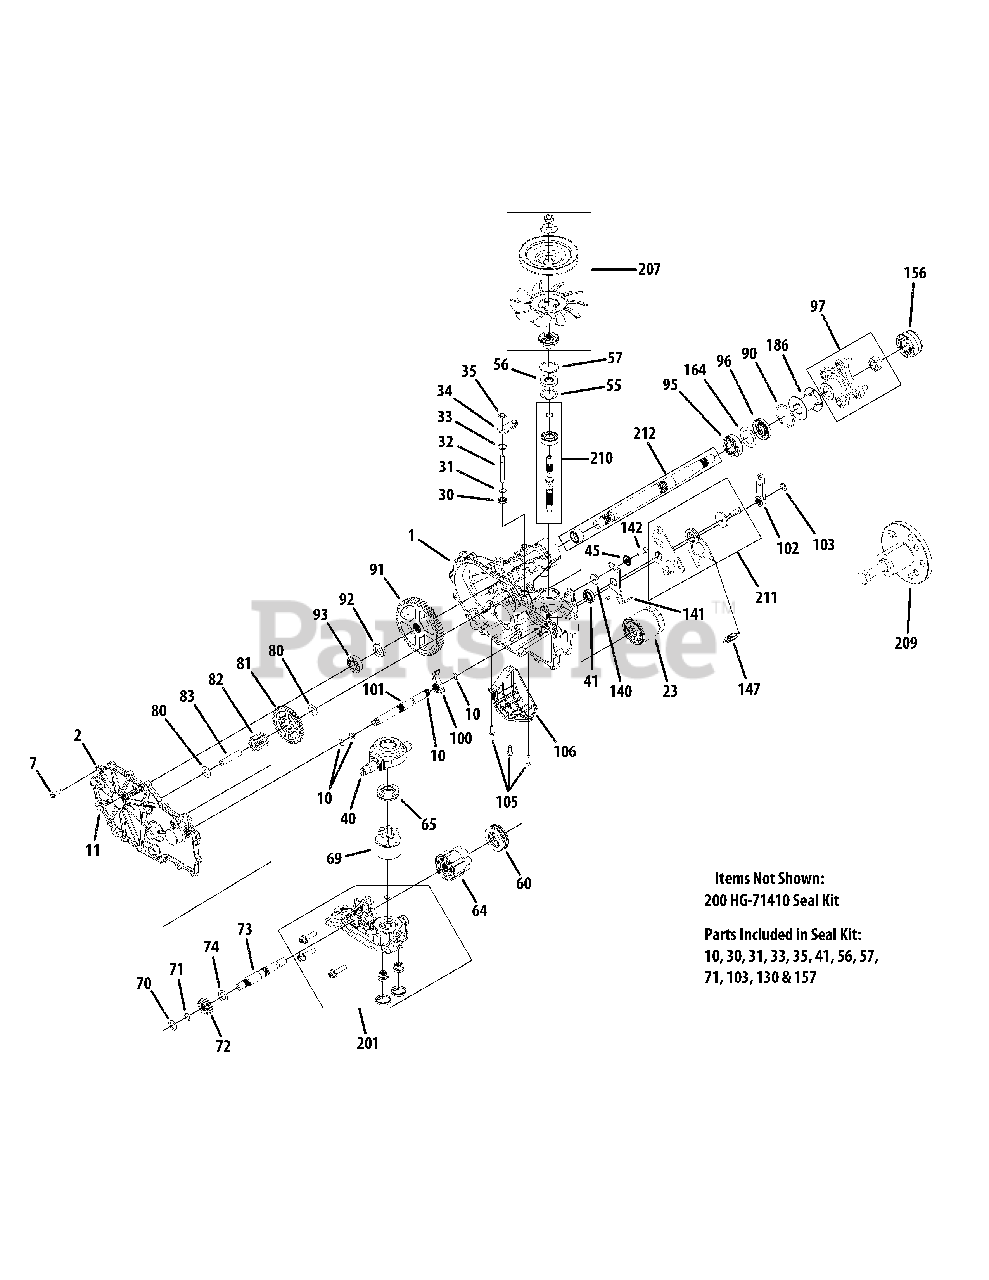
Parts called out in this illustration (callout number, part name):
1	Kit, Main Housing, LH Control
2	Kit, Side Cover, LH
7	Screw, Hex Washer
23	Filter, Spin-On 2.6 x 3.0
30	Seal, Lip, .375 x .75 x .25
31	Ring, Retaining .375 External
32	Rod, Bypass
33	Ring Retaining .750 Internal
34	Arm, Bypass
35	Ring, Ret .375 External
40	Trunnion, Swashplate
41	Seal, Lip 18 x 32 x 7
45	Washer, .34 x .88 x .06
55	Washer, 1.23 x 1.57 x .04
56	Seal, Lip 17 x 40 x 7
57	Ring Retaining Internal
60	Bearing, Thrust 35 x 62 x 18
64	Kit, 16cc Cylinder Block Assembly
65	Thrust Bearing, 30 x 52 x 13
69	Kit, Block, 7 Piston
70	Washer, .63 x 1.00 x .05
71	Ring, Reatining, Motor Shaft
72	Gear, 16T
73	Shaft, Motor
74	Washer, .71 x 1.16 x .04
81	Gear, 43T
82	Gear, 11T
83	Pin, Jackshaft
90	Ring, Retaining 2.25 Internal
91	Gear, 54T
92	Spacer, .750 x 1.00 x .257
93	Bearing, Ball 3/4 x 40mm x 12mm
95	Bearing, Ball 25.4 x 52 x 15
96	Seal, Lip, 1.0 x 2.06 x .38
97	Kit, Hub 4-Bolt
100	Pawl, Brake
101	Kit, Brake Shaft
102	Handle, Actuating
103	Ring, Retaining .438 External
105	Screw, Hex Washer 1/4-20 x .75
106	Guard, Filter, LH
140	Spacer, .320 x 1.005 x .150
141	Arm, Return Left
142	Socket Cap Screw, 5/16-24 x 7/8
147	Spring, Extension
156	Cap, Axle
164	Spacer, 1.355 x 2.035 x .021
186	Tube, Axle 2.03
200	Kit. Seal, ZT-2800
201	Kit, Center Section LH
207	Kit, Fan Pulley
207	Fan Only
207	Pulley Hub
209	Kit, Hub Puller
210	Kit, Input Shaft
211	Kit, RTN Bidirectional
212	Kit, Shaft Axle
